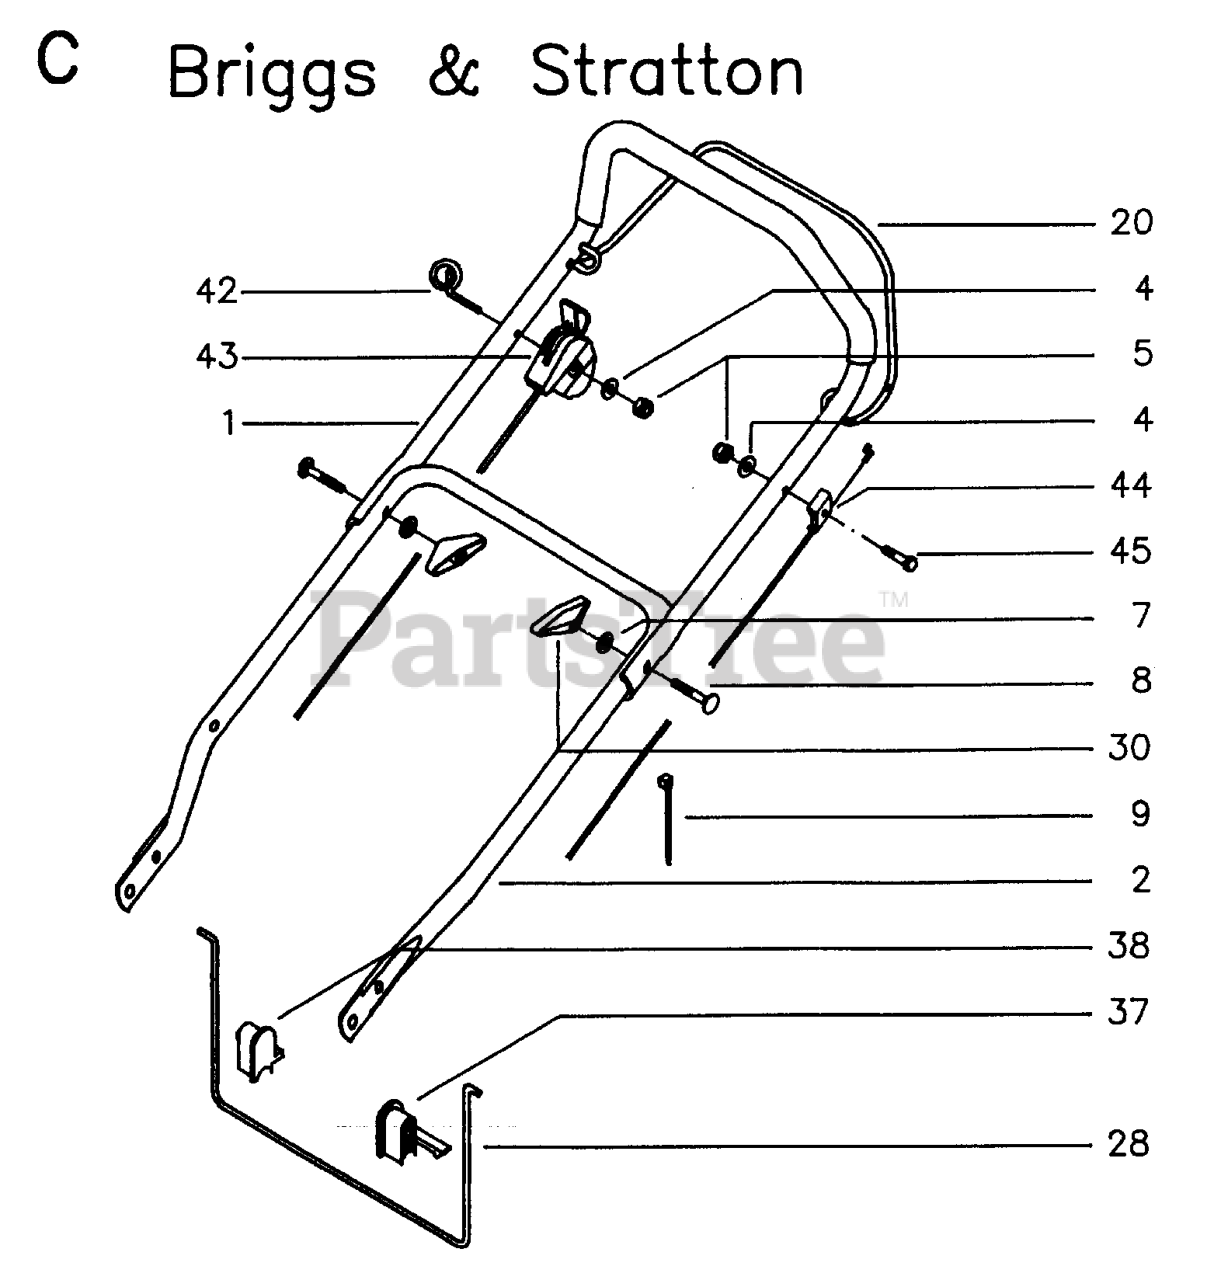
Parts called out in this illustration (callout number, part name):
2	LOWER HANDLE
5	LOCKNUT M6
28	HANDLE BAR
30	WINGNUT
43	REPL BY 517 81 00-00
44	WIRE MASTER 46
45	BOLT FLANGE
